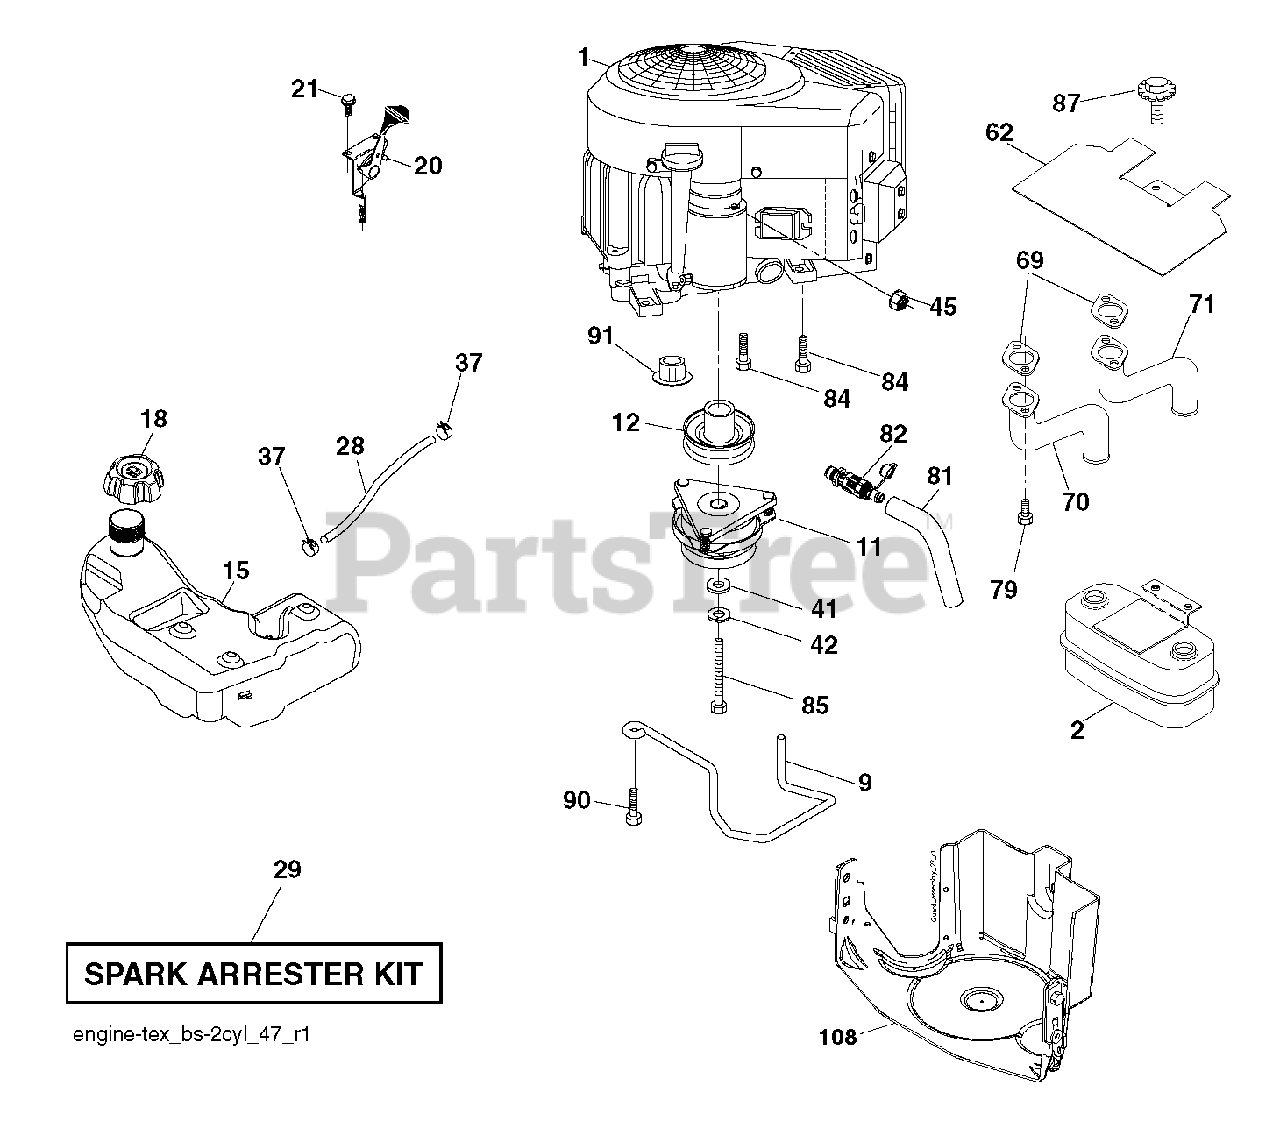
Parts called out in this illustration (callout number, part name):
2	MUFFLER.TWIN.CYL.LOW.TONE
9	KEEPER.BELT.ENGINE.4.2
11	CLUTCH ELECTRIC
12	PULLEY ENGINE
15	TANK.FUEL.4GAL
18	CAP.ASM.FUEL.TANK.3"BLACK
20	CONTROL.TH/CK.COBRA.B&S.TWN.
21	SCREW.#10 X 0.750.BOS THREAD
28	LINE.FUEL.20
29	ARRESTER SPARK (OPTIONAL)
37	HOSE CLAMP
42	LOCKWASHER
45	NUT
62	SHIELD.HEAT.MUFFLER
69	GASKET.MUFFLER
70	TUBE MANIFOLD LH
71	EXHAUST TUBE RH
79	SCREW.SOCKET.HEAD.5/16-18
81	TUBE, DRAIN OIL ASM.
82	VALUE.OIL.DRAIN
84	SCREW.3/8-16
85	BOLT HEX 7/16-20 X 3.75 GR. 5
87	BOLT 5/1618UNC X 3/4 W/ SEMS
90	SCREW 3/8-16X1
91	BUSHING.1.375OD
